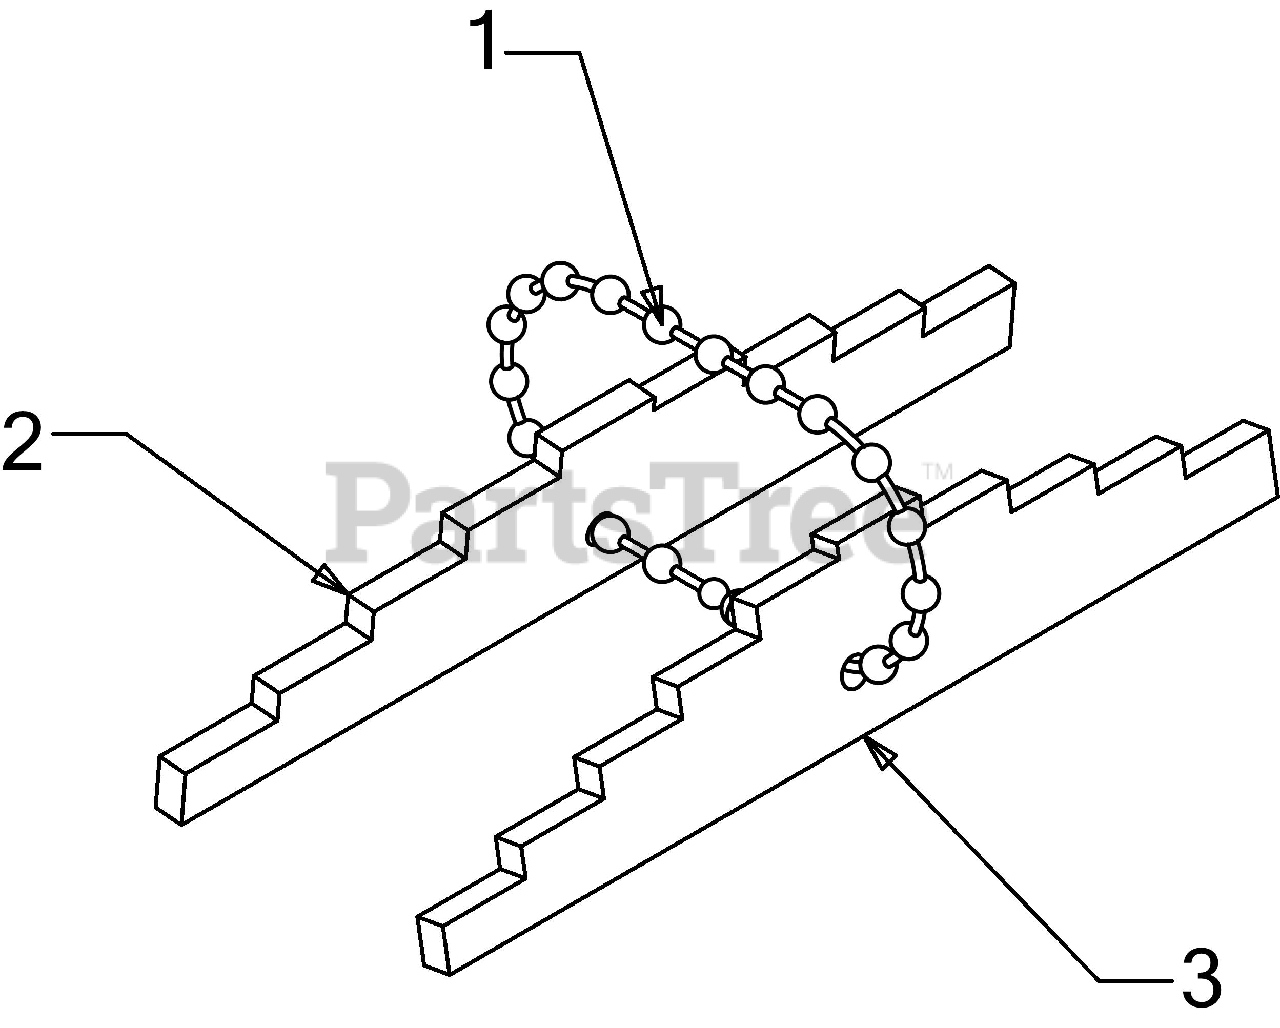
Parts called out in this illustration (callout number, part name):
1	GAUGE CALIBRATION CHAIN
2	CALIBRATION GAUGE - ODD
3	CALIBRATION GAUGE - EVEN
